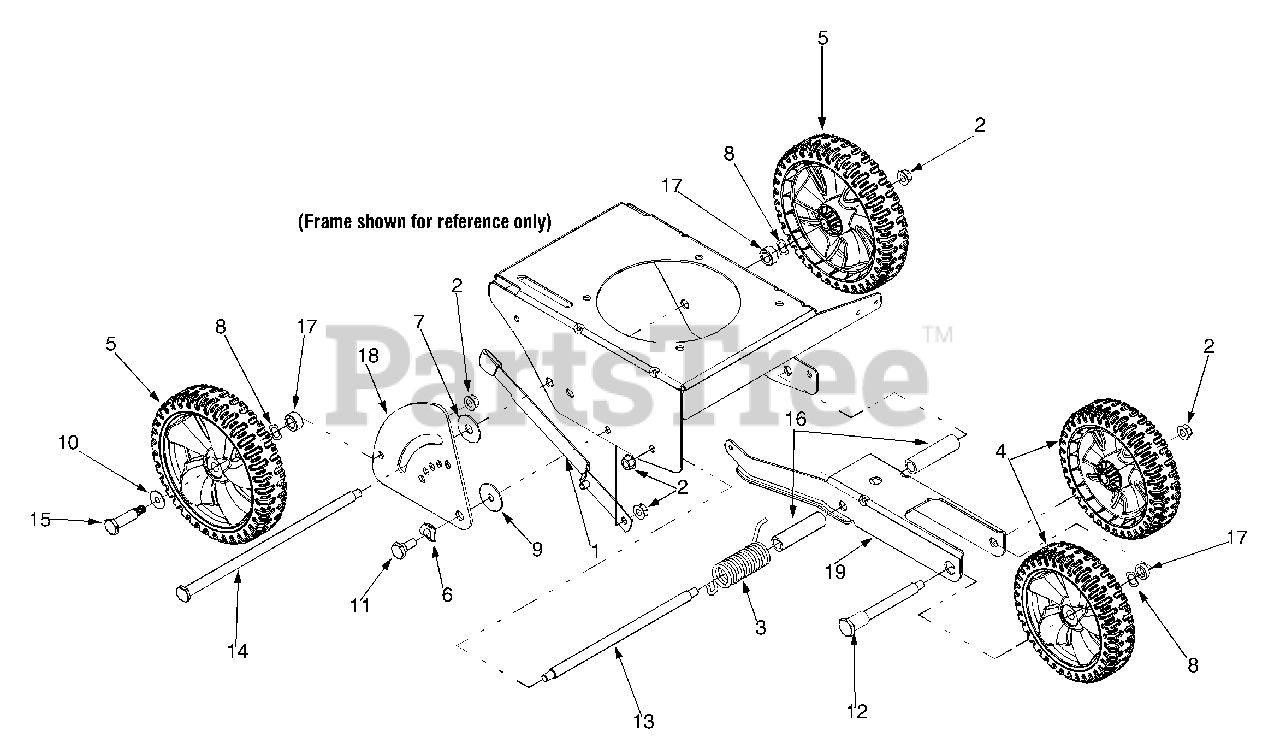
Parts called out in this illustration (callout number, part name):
1	Curb Height Adjustment Lever
2	Flange Lock Nut, 3/8-16
3	Torsion Spring
4	Wheel 7 x 1.75
5	Wheel 8 x 1.75
6	Spring Washer,.500 x 1.00
7	Flat Washer,.51 ID x 1.5 OD
8	Wave Washer,.531 ID x.781 OD
9	Washer,.385 x 1.5
10	Flat Washer,.510 x 1.00
11	Shoulder Screw,.50 x.27
12	Shoulder Screw,.50 x 4.62
13	Shoulder Screw,.50 x 9.36, 3/8-16
14	Shoulder Screw,.50 x 11.61
15	Shoulder Screw,.498 x 2.045
16	Spacer,.525 x.688
17	Spacer,.505 ID x.88 OD
